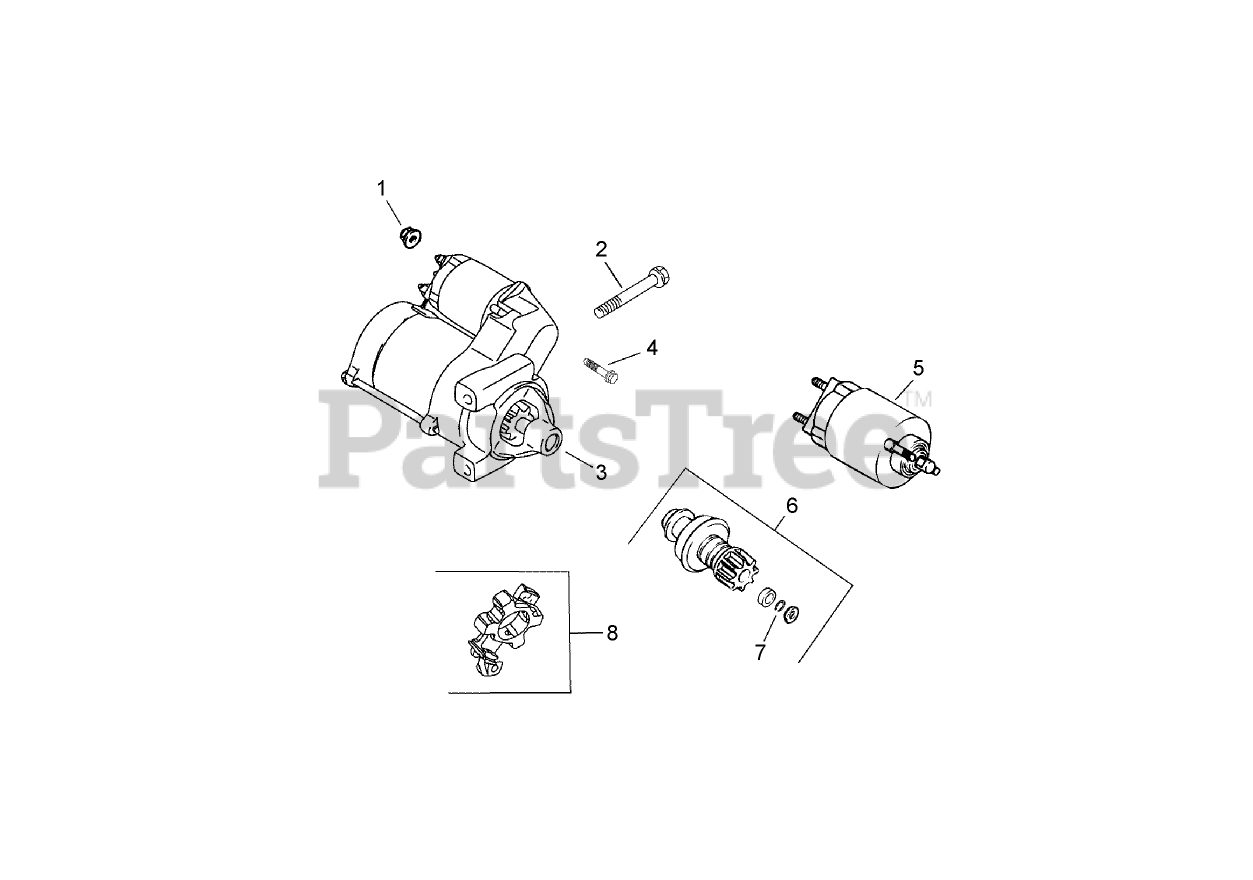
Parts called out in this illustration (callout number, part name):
1	NUT-FLANGE (M8X1.25)
2	SCREW-FLANGE (M8X1.25X80)
3	Starter ASM (Includes 4-8) Note: Service Starter and components according to Starter brand and number.
4	SCREW-TORX HEAD, EXTERNAL
5	Solenoid Kit (Includes 4)
6	Pinion Drive Kit (Includes 7)
7	RING-RETAINING
8	BRUSH HOLDER KIT
